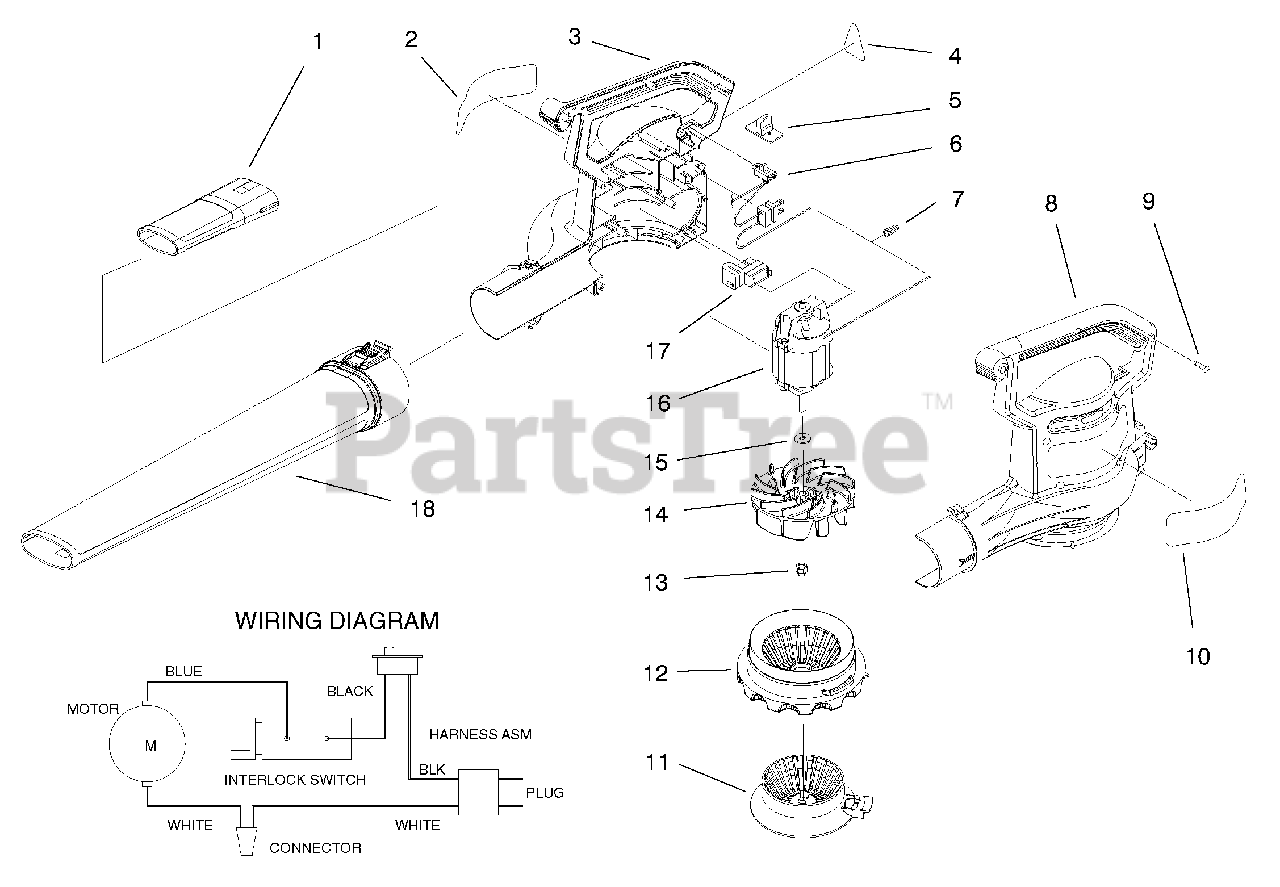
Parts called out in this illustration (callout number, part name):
1	Insert-Tube
2	Decal-Logo
3	Housing-R.H.
4	Decal-Information
5	Cover-Switch
6	Harness Assembly
7	Connector-Wire Nut
8	Housing-L.H.
9	Screw-Phillips Hd. Tap.
10	Decal-Warning
11	Choke-Air
12	Cover-Inlet
13	Nut-Cap Hex
14	Impeller
17	Switch-Interlock
18	Tube-Blower
